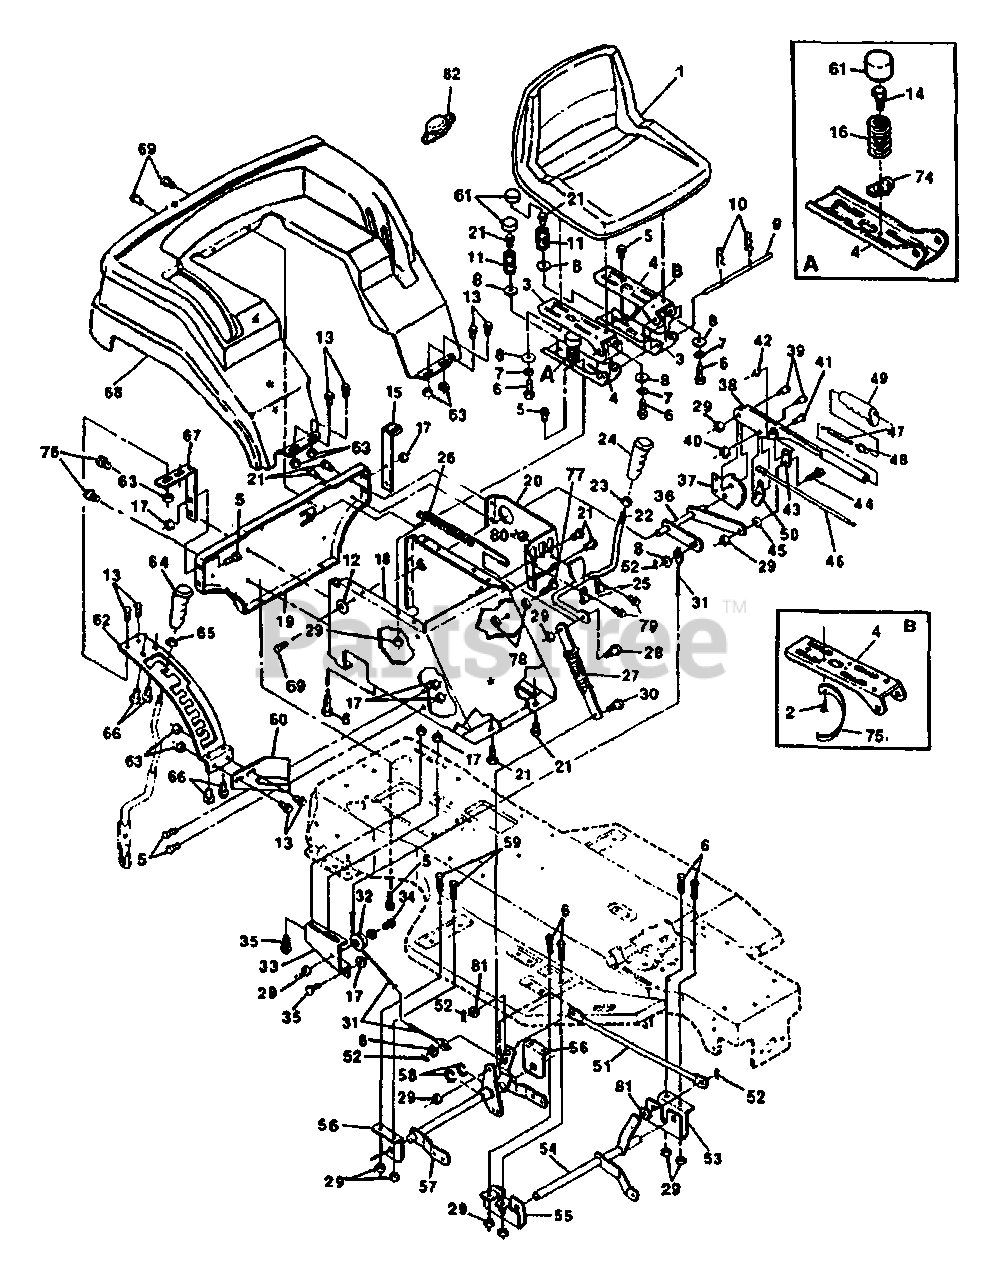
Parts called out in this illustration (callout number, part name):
1	SEAT.SWEDISH.RIDER
3	CHANNEL SEAT
5	SCREW
6	SCREW
7	WASHER
8	WASHER
11	SPRING
12	WASHER - 15X7.3X1.6
13	SCREW
15	SUPPORT
21	SCREW
23	NUT
25	CLAMP
28	REPL BY 533 30 59-89
29	NUT
30	SCREW
35	SCREW
40	NUT
42	RETAINING RING
45	WASHER
58	RETAINING RING
59	SCREW
61	CAP
63	NUT
65	NUT
67	REPL BY 533 30 53-80
69	SCREW
74	SPRING CLAMP
76	SCREW
77	SCREW
79	SCREW
80	NUT
81	WASHER
82	ANTI-START SWITCH CPL
